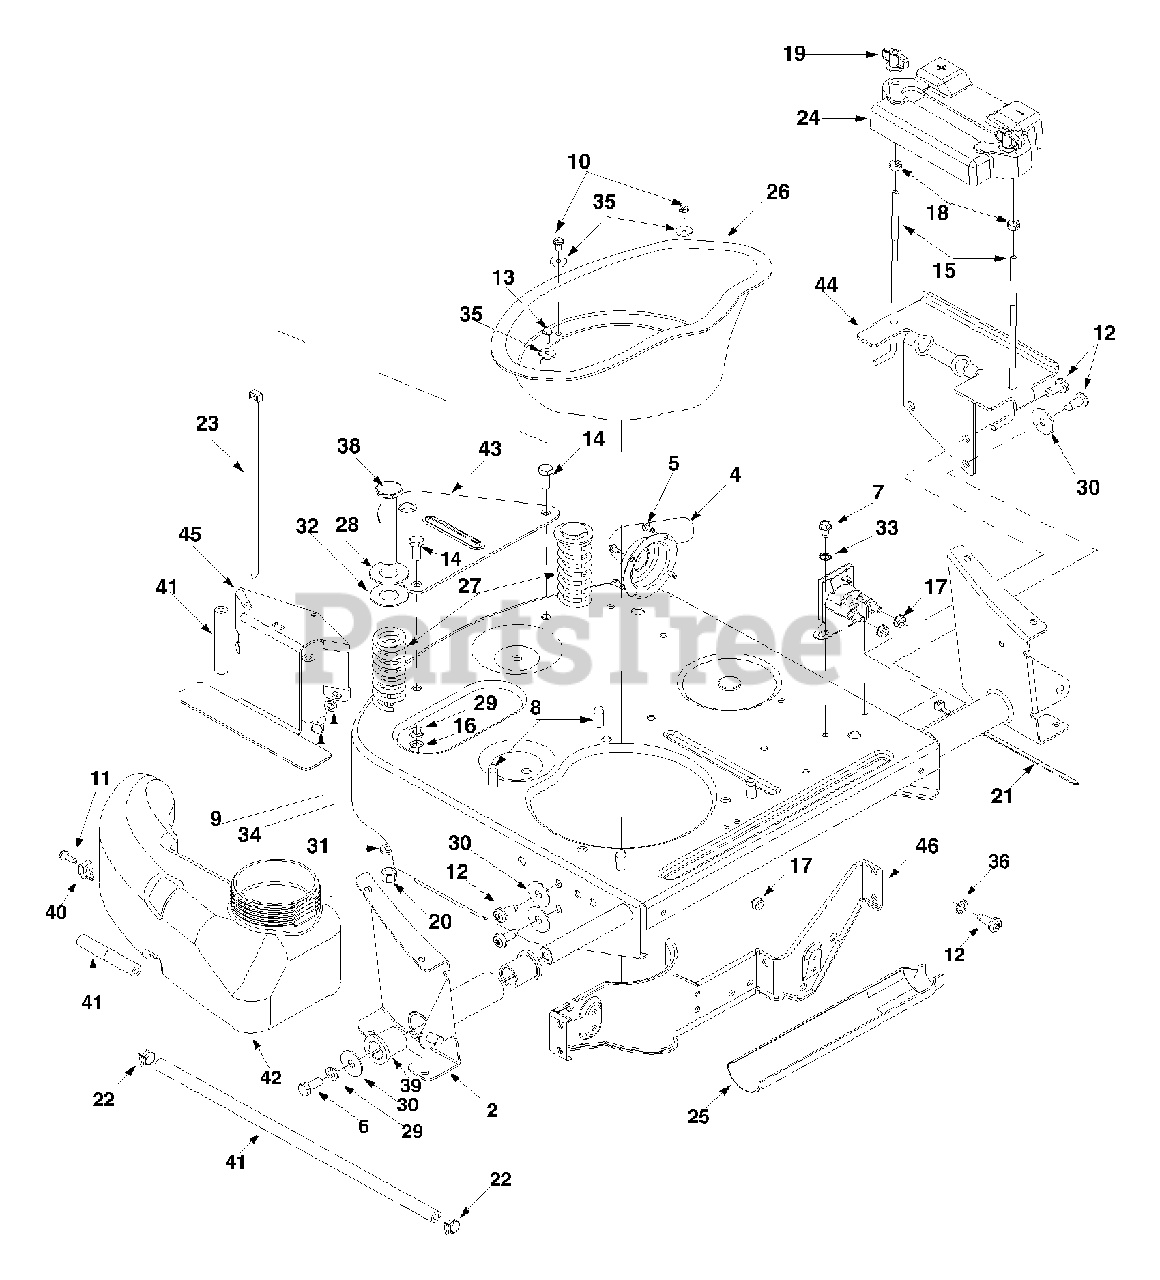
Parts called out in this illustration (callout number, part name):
5	Hex Fl. Screw #8-32 x 0.375
6	Hex Screw 5/16-24 x .75" Gr.5
7	Self-Tapping Screw
8	TT Screw 3/8-16 x 1.0"
9	Hex Screw 1/4-20 x 0.5"
10	Hex Slot Sems Screw #10-32 x 0.38
11	TT Screw #10-32 x 0.625"
12	TT Screw 5/16-18 x 0.75"
13	Machine Screw #10-32 x 0.5"
14	Hex Screw 5/16-18 x 0.75"
15	Battery Hold-Down Rod
16	Hex Nut 5/16-18
17	Hex Sems Nut 1/4-20
18	Lock Nut 1/4-20
19	Wing Nut with Bell Washer
20	Hex Nut
21	Cable Tie
22	Hose Clamp
23	Cable Tie
24	Battery Cover
25	Oil Drain Sleeve
26	Engine Duct
27	Compression Spring
28	Rubber Washer
29	Lock Washer
30	Flat Washer
31	Lock Washer
32	Flat Washer
33	Lock Washer
34	Lock Washer
35	Flat Washer
36	Lock Washer
38	Shoulder Screw
39	Flange Bearing
40	Throttle Casing Clamp
41	Fuel Line Hose
42	Fuel Tank
